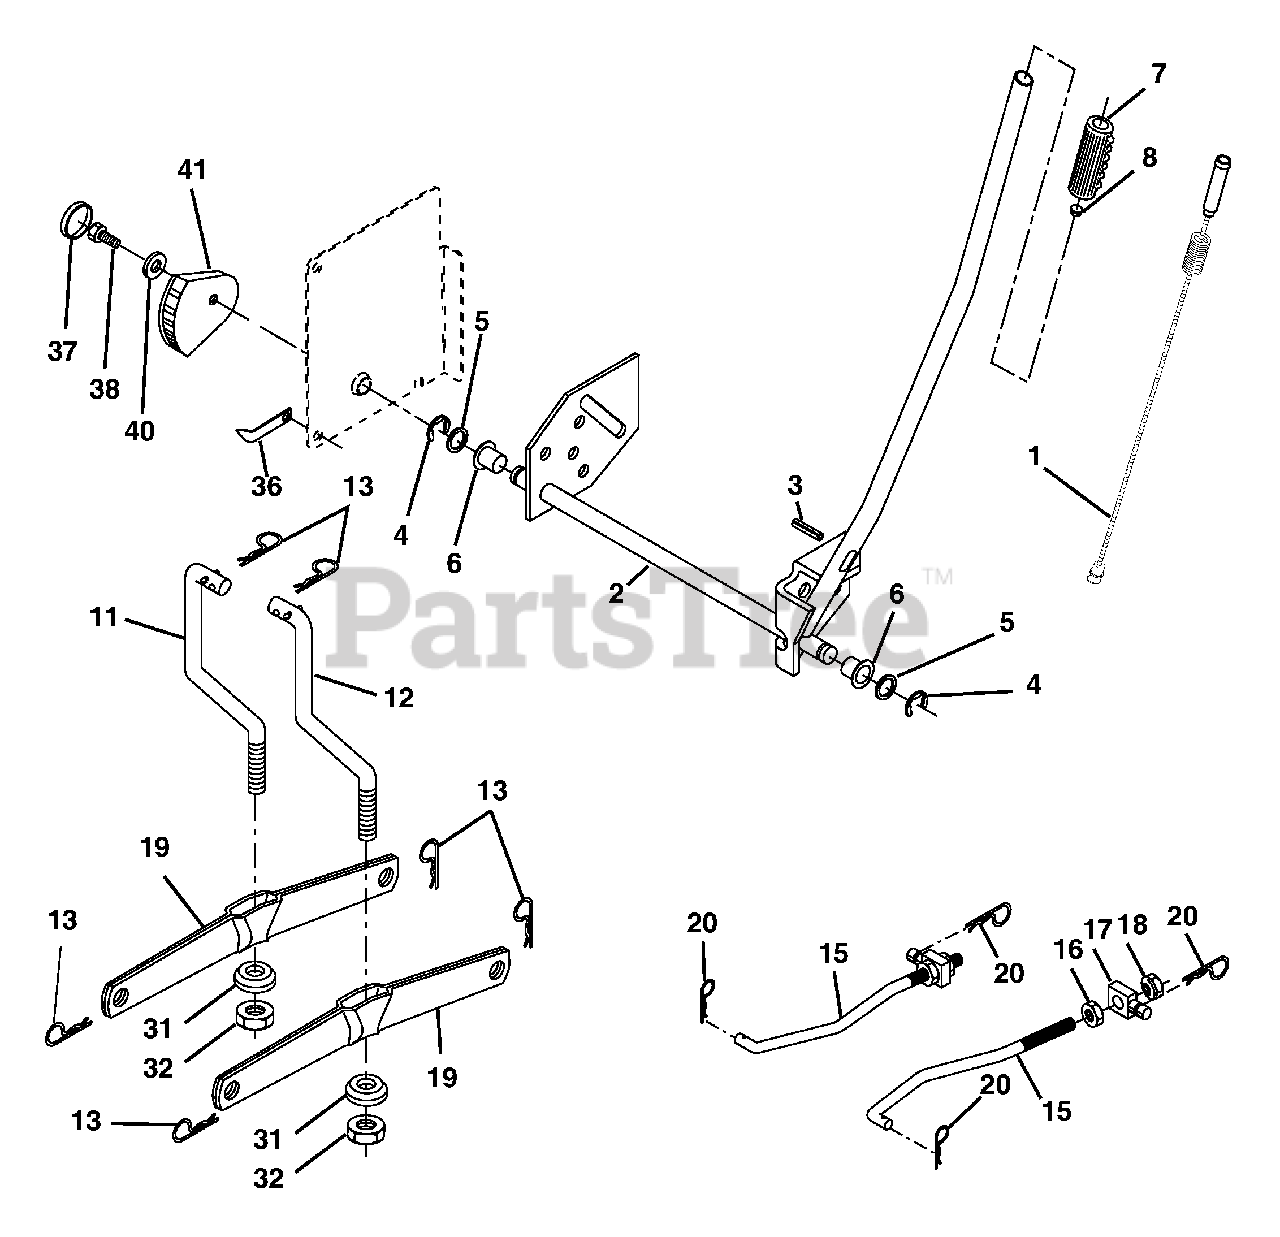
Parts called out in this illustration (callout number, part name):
1	Wire Asm Inner/Sprg W/plunger
2	Shaft Asm Lift RH w/Inf
3	Pin Groove 5/16 Dia x 1.875
4	E Ring #5133-62
5	Washer 21/32 x 1 x 21 Ga.
6	Bearing Nylon Blk 629 Id
7	Grip Handle
8	Button Plunger
11	Link Lift LH Fixed Length
12	Link Lift RH Fixed Length
13	Retainer Spring
15	Link Front
16	Nut Jam Hex 1/2-13 unc
17	Trunnion
18	Nut Lock W/Wsh 1/2-13 unc
19	Arm Suspension Rear
20	Retainer Spring
31	Bearing Pvt Lift
32	Nut Crownlock 3/8 - 24
36	Pointer Height Indicator
37	Plug Hole 1.485/1.515 Dia.
38	Screw 5/16-18 x 1
40	Washer 11/32 x 1-1/2 10 Ga.
41	Indicator Height
